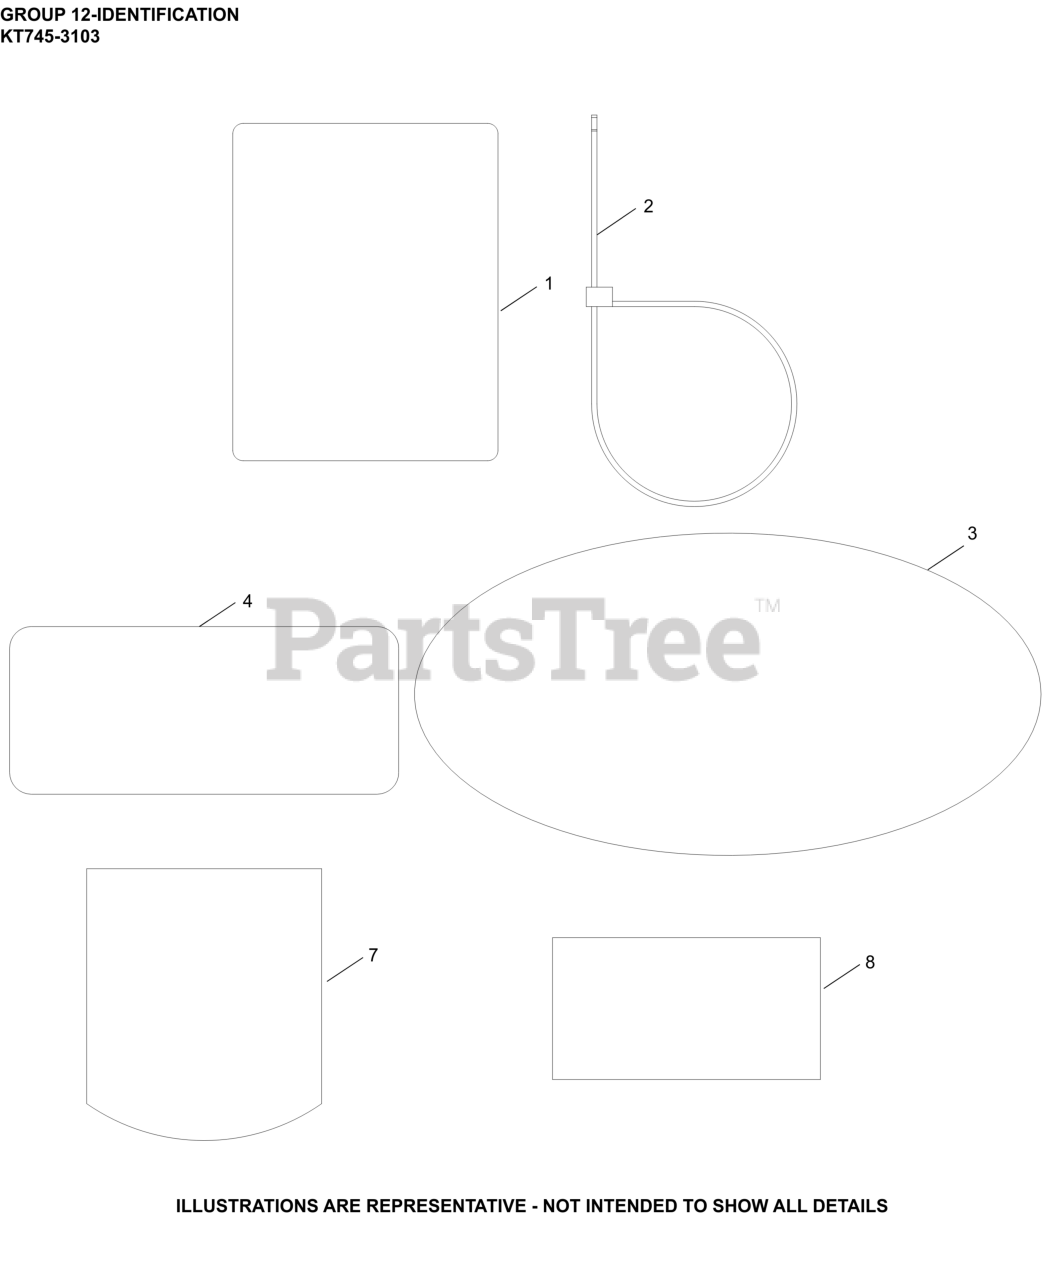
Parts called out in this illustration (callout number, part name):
1	LABEL, CLEAR LAMINATION
3	LABEL, PRO PERFORMANCE FILTRATION SYSTEM
4	LABEL, CANADIAN COMPLIANCE
7	LABEL, 7000 SERIES KT745 (26 HP,PRO A/F)
8	DECAL, USA
